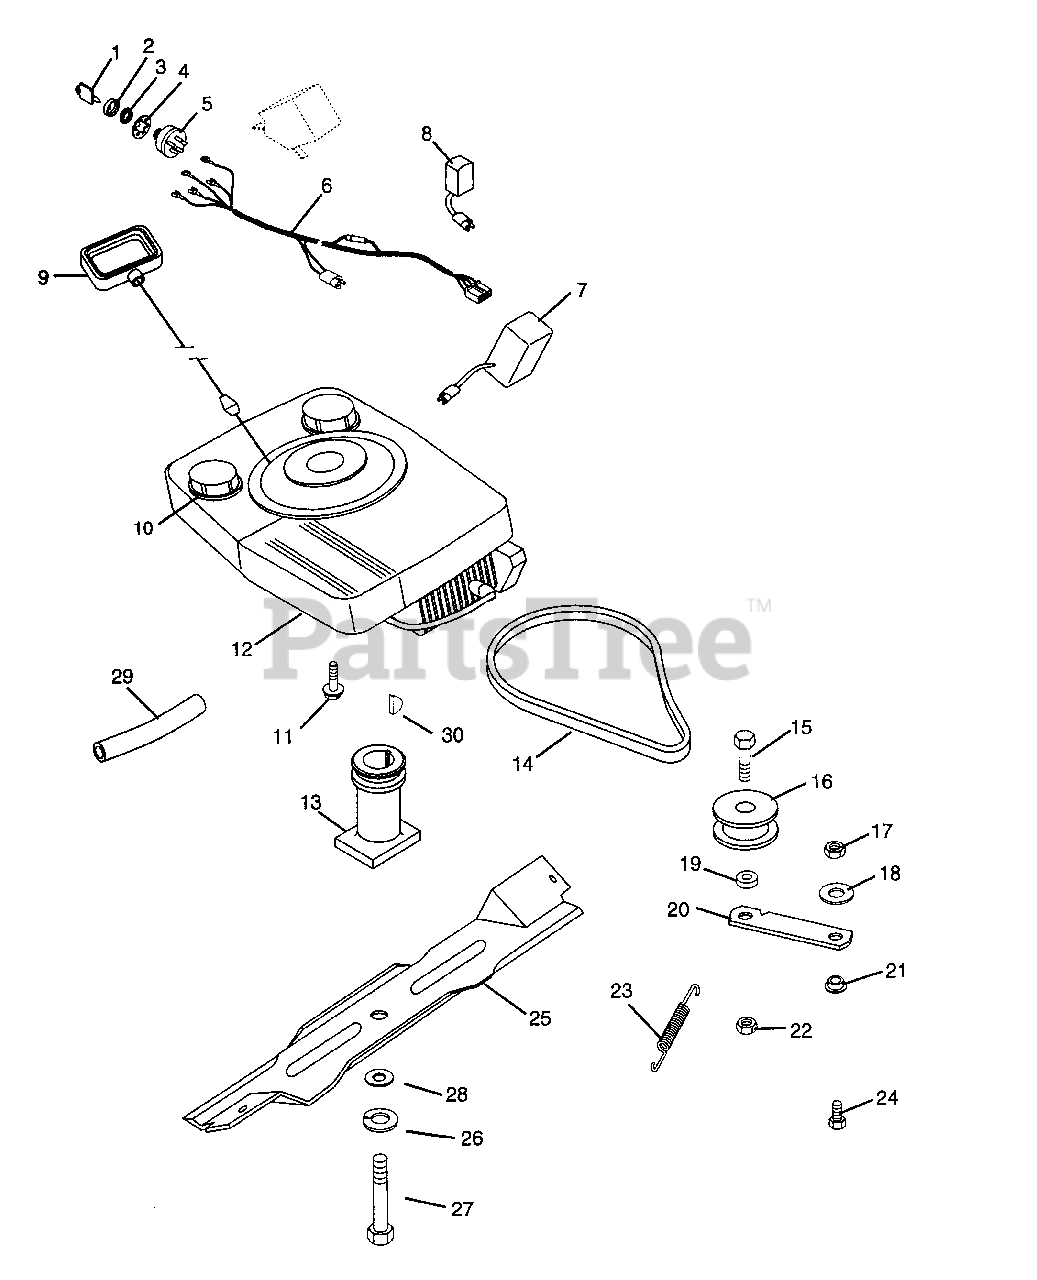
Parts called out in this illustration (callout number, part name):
1	KEY -W/CAP
2	CAP - IGNITION SWITCH
3	NUT-PANEL .625-32 GRECO
4	WSHR-LK-INT .625X.045 YWZC
5	KEY SWITCH
6	WIRE HARNESS
7	BATTERY,
8	BATTERY CHARGER
9	HANDLE, RECOIL START
10	FUEL CAP
11	SCR-TAP .375-16X1.00 HWH TR YZ
12	ENG, 5 HP KAW (W/PRESS LUBE)
12	ENGINE ROBIN 6HP. PR LUBE.
12	ENGINE TECUMSEH 5HP CENTURA V
12	ENGINE BRIGGS 5.5HP DIAMOND.
12	ENGINE TECUMSEH 6HP VECTOR VER
12	ENGINE TECUMSEH 5.5HP CENTURA
13	PLZ READ SERVICE LETTER #L-429
13	BLADE ADAPTER
13	BLADE ADAPTER 1.00 DIA SPLINE
14	V-BELT, 3L-COGGED
15	@BLT-HEX .44-14X1.25 GR5 YWZC
16	IDLER-FLAT 1.75 X .47
17	@NUT-LK-CTR .31-18 YWZC
18	WSHR-FL-STL .323X.625X.062 YWZ
19	SPACER .52 X .45 X .34
20	IDLER ARM
21	BSHG-FLG .325X.501X.250X1.120
22	@NUT-LK-CTR .44-14 YWZC
23	SG-TENS .043X.44X3.31 WLD 5.8
24	@BLT-HEX .31-18X.75 GR5 YWZC
25	21" MOWER BLADE
25	BLADE, 21" LM MULCHING
26	@WSHR-LK .38X.094 REG YWZC
27	BLT-HEX .38-24X2.0 YWZC
28	WSHR-HDND-THR .390X1.50X.125PL
29	DRAIN HOSE
30	KEY-WDRF .156X.625X.25 SAE 6
